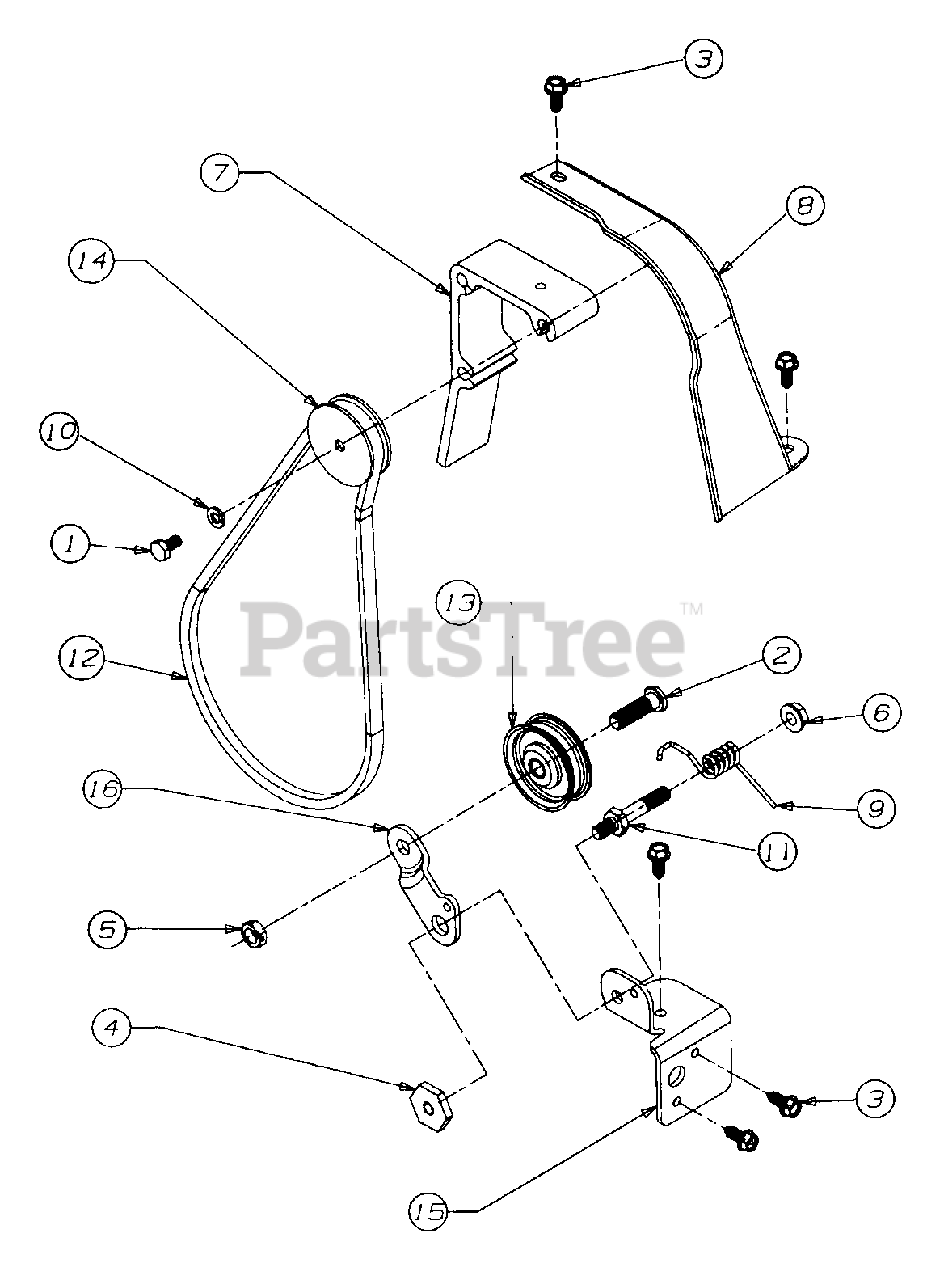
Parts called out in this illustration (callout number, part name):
1	SCREW-HEX
2	SCREW-HEX
3	SCREW-HEX
4	NUT-HEX SHOULDER
5	NUT-HEX LOCK
6	NUT-HEX LOCK FLANGE
7	ADAPTER-MOUNTING
10	WASHER-LOCK
11	BOLT-IDLER
12	V-BELT
13	IDLER-FLAT
